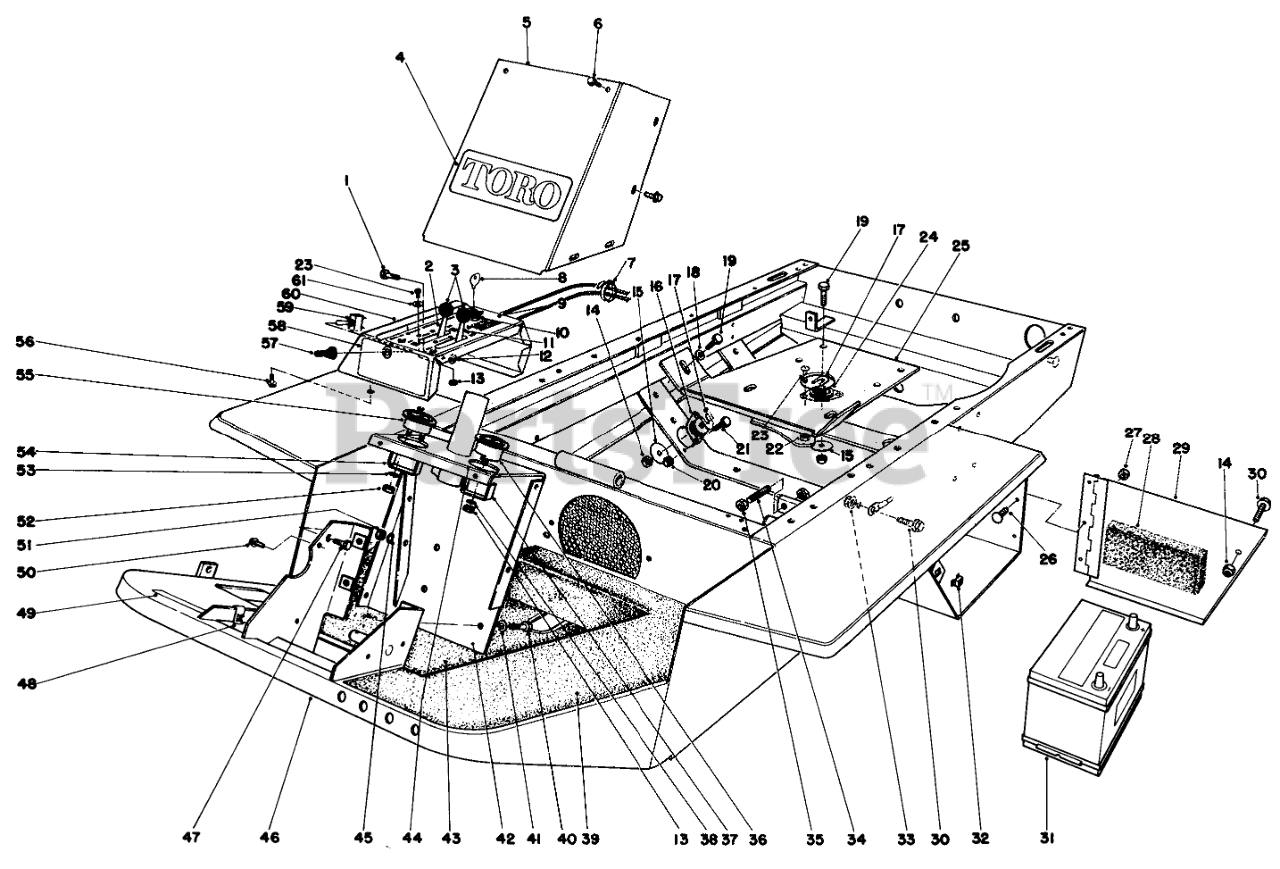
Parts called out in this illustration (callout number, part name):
1	SCREW-HH
2	CHOKE CONTROL
4	Decal
5	Tower Cover
6	SCREW-HHFTF
7	TIE-CABLE
8	Key
9	Decal-Instrument Panel
10	SWITCH
11	THROTTLE CONTROL
12	WASHER-FLAT
13	NUT-HEX
14	NUT-LOCK, NI
15	WASHER
16	ENGINE RUBBER MT
17	SHIM-AXLE
18	WASHER-FLAT
19	SCREW-HH
20	NUT-LOCK, NI
21	SCREW-HH
22	NUT-LOCK, NI
23	10-24 X 5/8 PAN HD MS
24	RUBBER MOUNT
25	Base-Engine
26	SCREW-HSBH
27	NUT-LOCK, NI
28	BATT BOX FOAM
29	Battery Cover
30	SCREW-HHF
31	Battery Assy.
32	RETAINER NUT
33	NUT-HHF, WHIZ
34	STOP PIN PP
35	NUT-JAM
36	HOUR METER
37	BRACKET F/W
38	WASHER-LOCK, INT
39	NON SKID (TUNNEL)
40	SCREW-HH
41	WASHER-LOCK
42	Steering Post
43	NON-SKID-FLOOR
44	INSTRUCTION DECAL
45	WASHER-LOCK
46	FRAME WA
47	SCREW-HH
48	SPEED NUT
49	DECAL-PEDAL, TRACTION
50	SCREW-HWH
51	NUT-HEX
52	NUT-HEX
53	WASHER-FLAT
54	MTG CLAMP F/W GUAGE
55	AMMETER GAUGE ASSY
56	SCREW-THD FRM,HWH
57	BOOT-SWITCH
58	BY-PASS DECAL
59	Switch-Toggle (Incl. Ref.#57)
60	Instrument Panel
61	WASHER-LOCK
